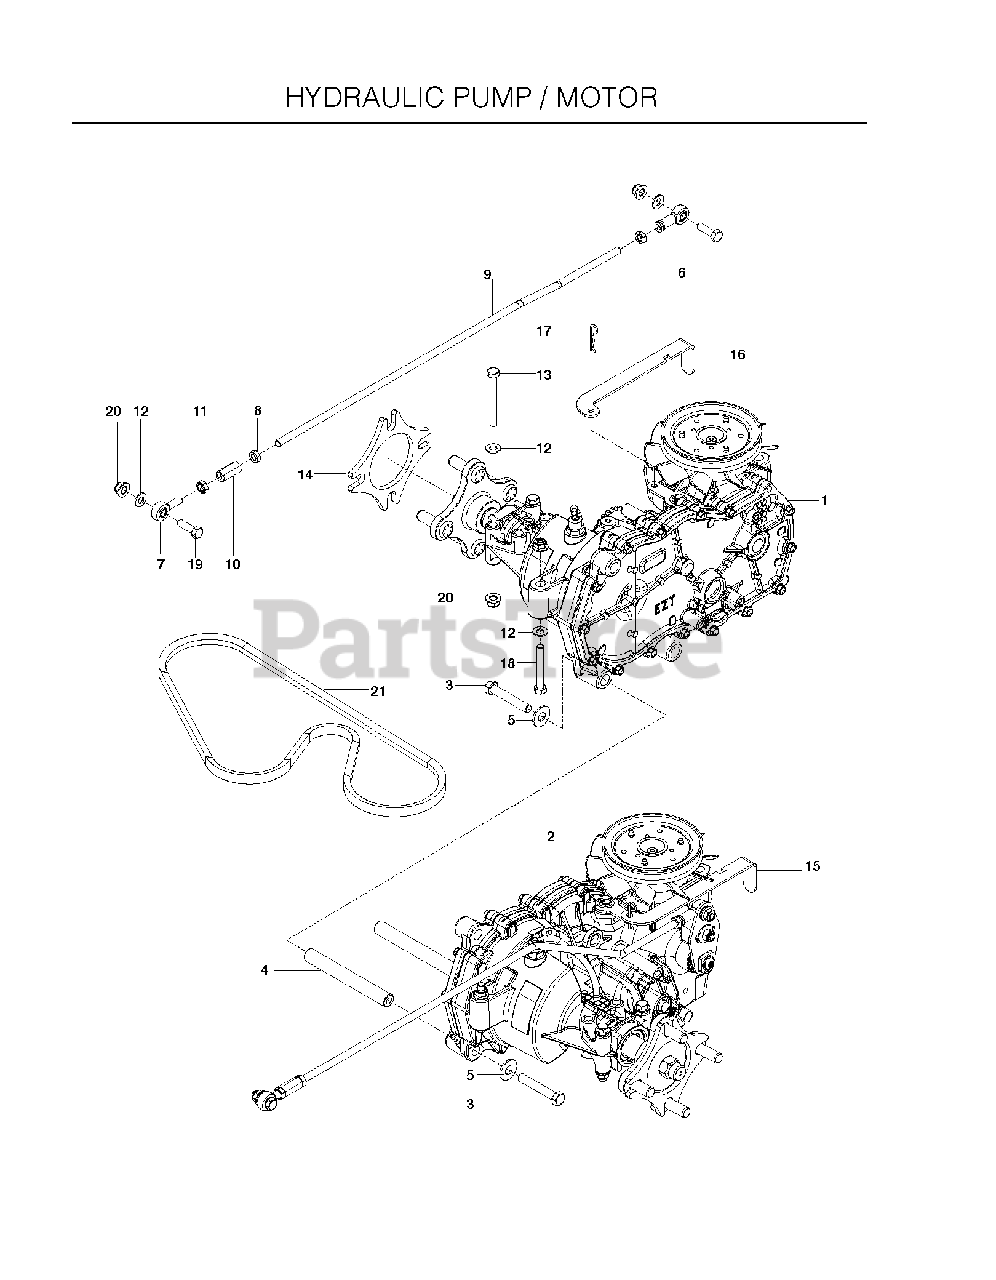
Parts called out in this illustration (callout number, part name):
1	HG_HYDRO RH
2	HG_HYDRO LH
3	HCS 3/8C X 2 1/4
4	HYDRO SPACER
5	WASHER 3/8 FLAT
6	RH ROD END
7	ROD.END.LH
8	NUT 5/16-24 UNF HEX JAM
9	CONTROL ROD
10	ROD END COUPLER
11	NUT 5/16F LEFTHAND
12	FLAT WASHER 5/16 SAE
13	HCS 5/16C X 2-3/4
14	SPACER, WHEEL
15	RELEASE LEVER LH
16	RELEASE LEVER RH
17	HAIRPIN #2
18	CAPSCREW
19	HCS 5/16C X 1
20	5/16-18 NYLOC FLANGE NUT
21	BELT 30 ZEZT
